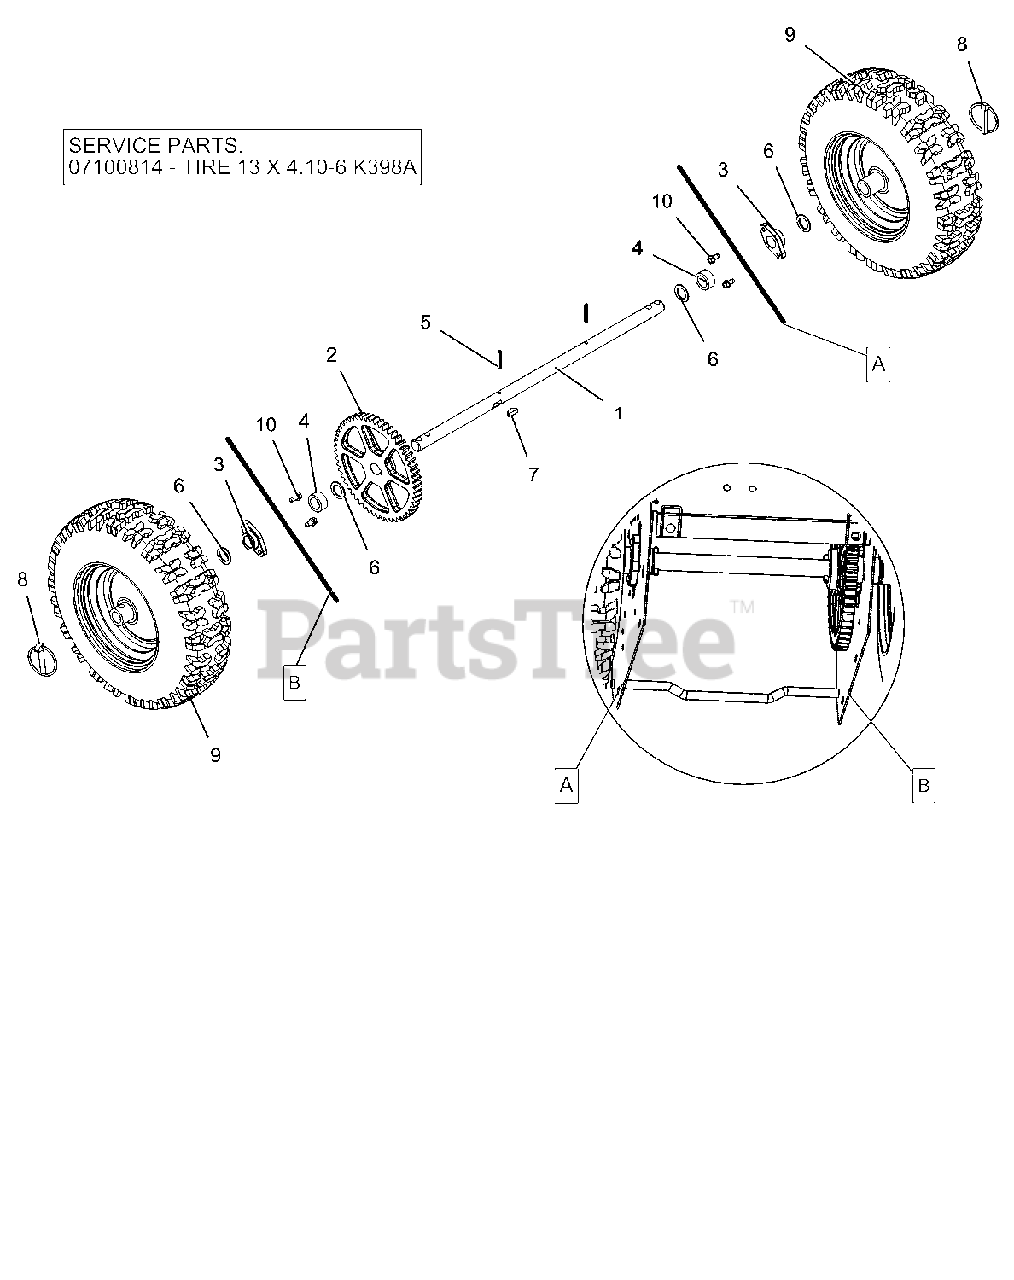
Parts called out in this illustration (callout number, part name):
1	SHAFT, AXLE
2	SPUR GEAR, 54T .75ID X 6.75PD
3	BSHG .75X1.125X.65
4	BSHG-SLV .766 X 1.125 X .500
5	PIN-ROLL .188X1.25
6	WSHR-FL-STL.754X1.125X.062YWZC
7	KEY-WDRF .25X.750X.313 SAE91
8	PIN-LOK .31X1.75
9	TIRE/WHEEL, 13X4.10-6 K398A
9	TIRE, 13" K398A
9	TUBE
10	SCR-TAP .25-20X.50 HWH TR YWZ
